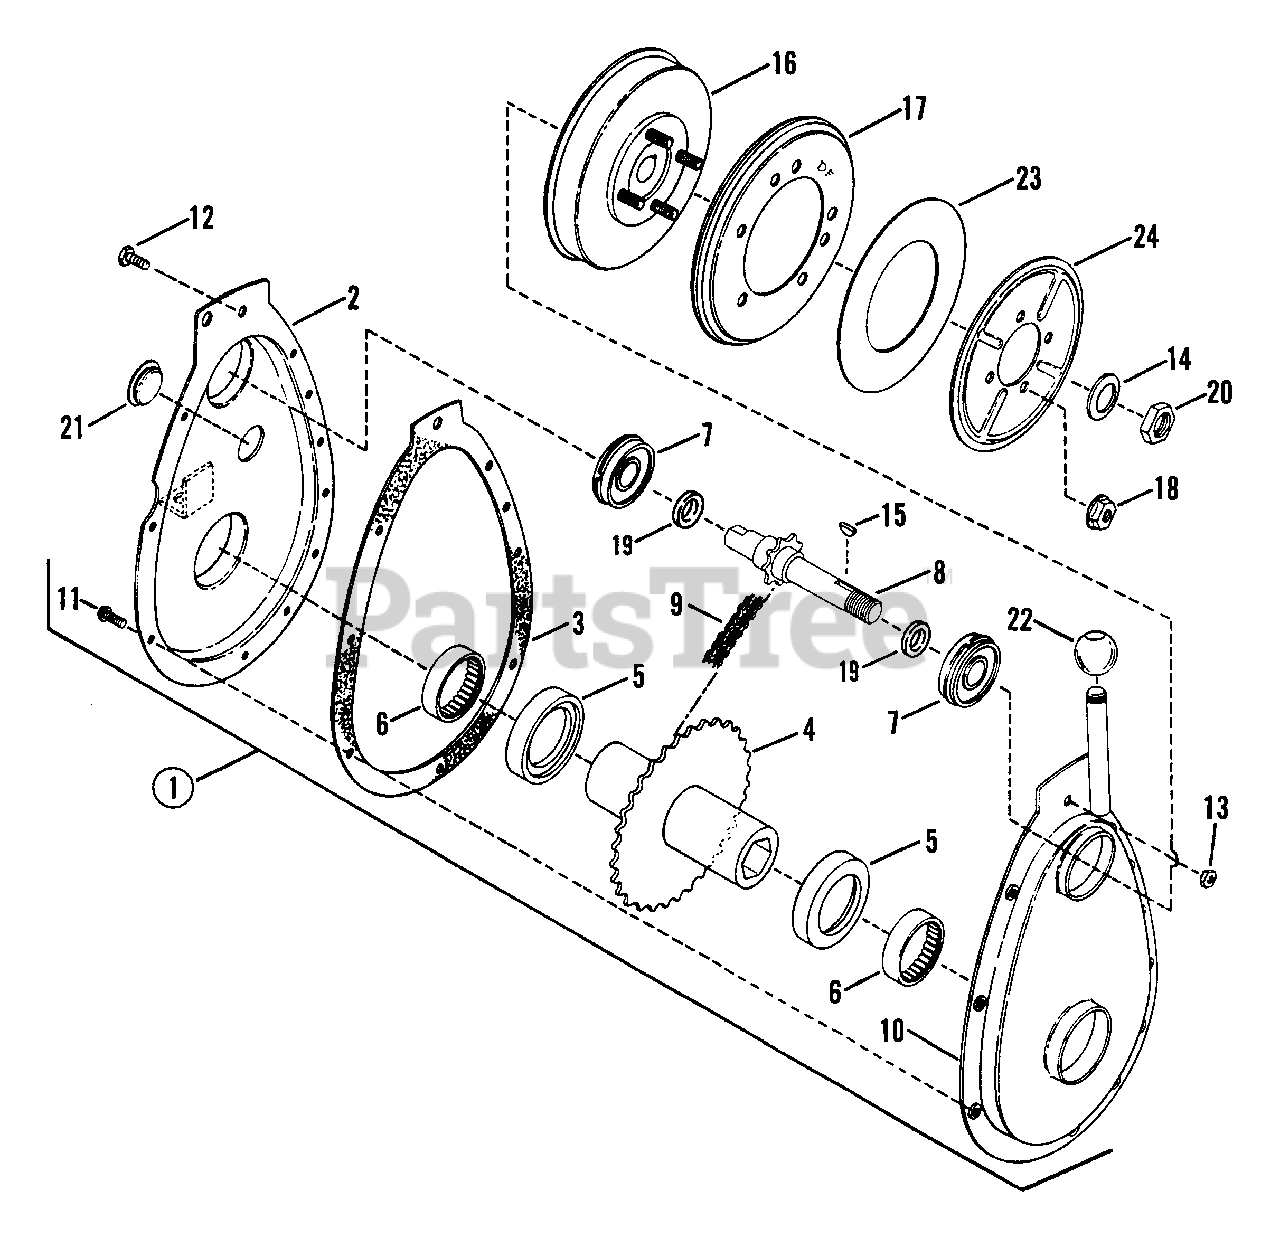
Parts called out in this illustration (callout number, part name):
1	ASSEMBLY, Primary Chain Case
2	COVER, Case
3	GASKET, Case/Cover
4	HUB & SPROCKET
5	THRUST-WASHER
6	BEARING, Needle
7	BEARING, Ball
8	SHAFT, Input
9	CHAIN
10	CASE, Sprocket
11	SCREW, #10-24 x 1/2" Hex Washer Self-Tap (Torx)
12	SCREW, 1/4-20 x 5/8" Hex Head Cap, Gr.5
13	NUT, 1/4-20 Hex Center Lock
14	WASHER, Bellville
15	KEY, 1/8 x 5/8 Woodruff
16	HUB, Driven Disc
17	DISC, Driven
18	NUT, 5/8-18 Hex Center Lock
19	O-RING, 5/8
20	NUT, 5/8-18 Hex Flange Lock, Grade 5
21	PLUG
22	BUSHING, Primary Clutch Ball
23	WASHER, Thrust
24	PLATE
